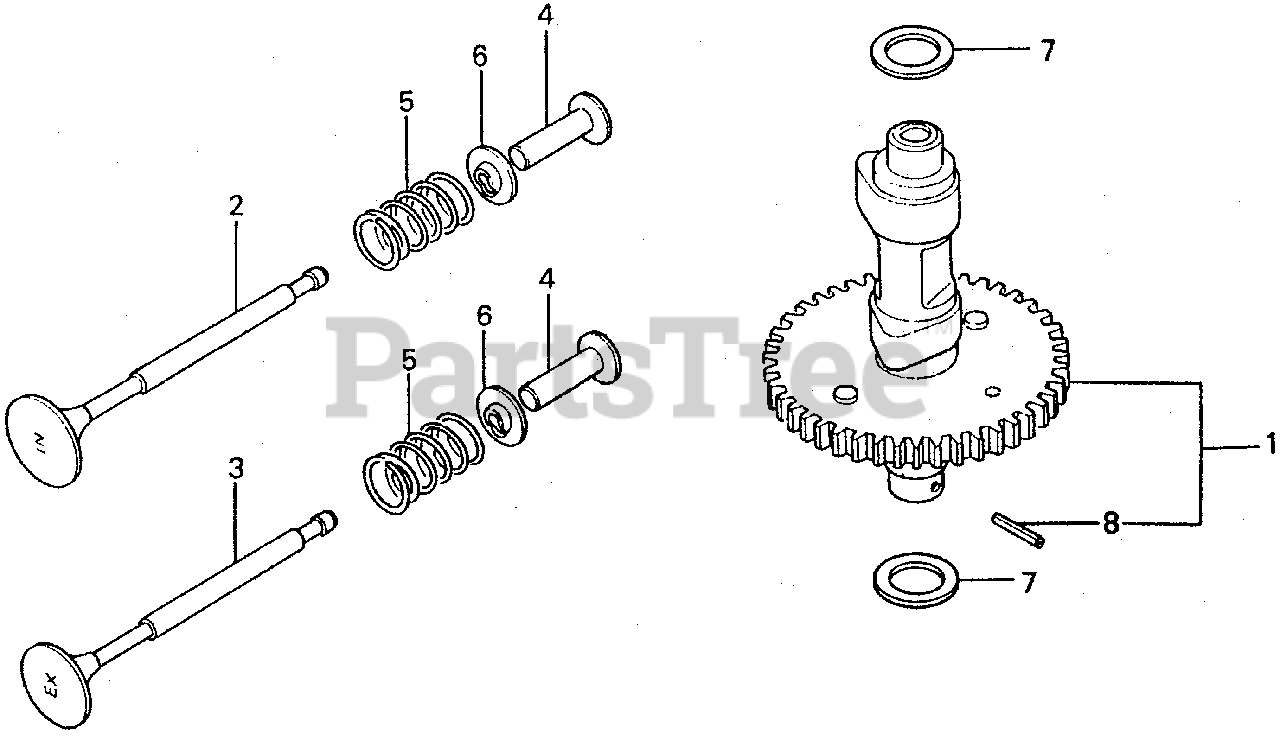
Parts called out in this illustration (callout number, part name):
1	CAMSHAFT ASSY.
2	VALVE, IN.
3	VALVE, EX.
4	LIFTER, VALVE (31.33)
4	LIFTER, VALVE (31.51)
4	LIFTER, VALVE (31.66)
5	SPRING, VALVE
6	RETAINER, VALVE SPRING
7	WASHER, THRUST (18MM)
8	PIN, SPRING (2.5X16)
